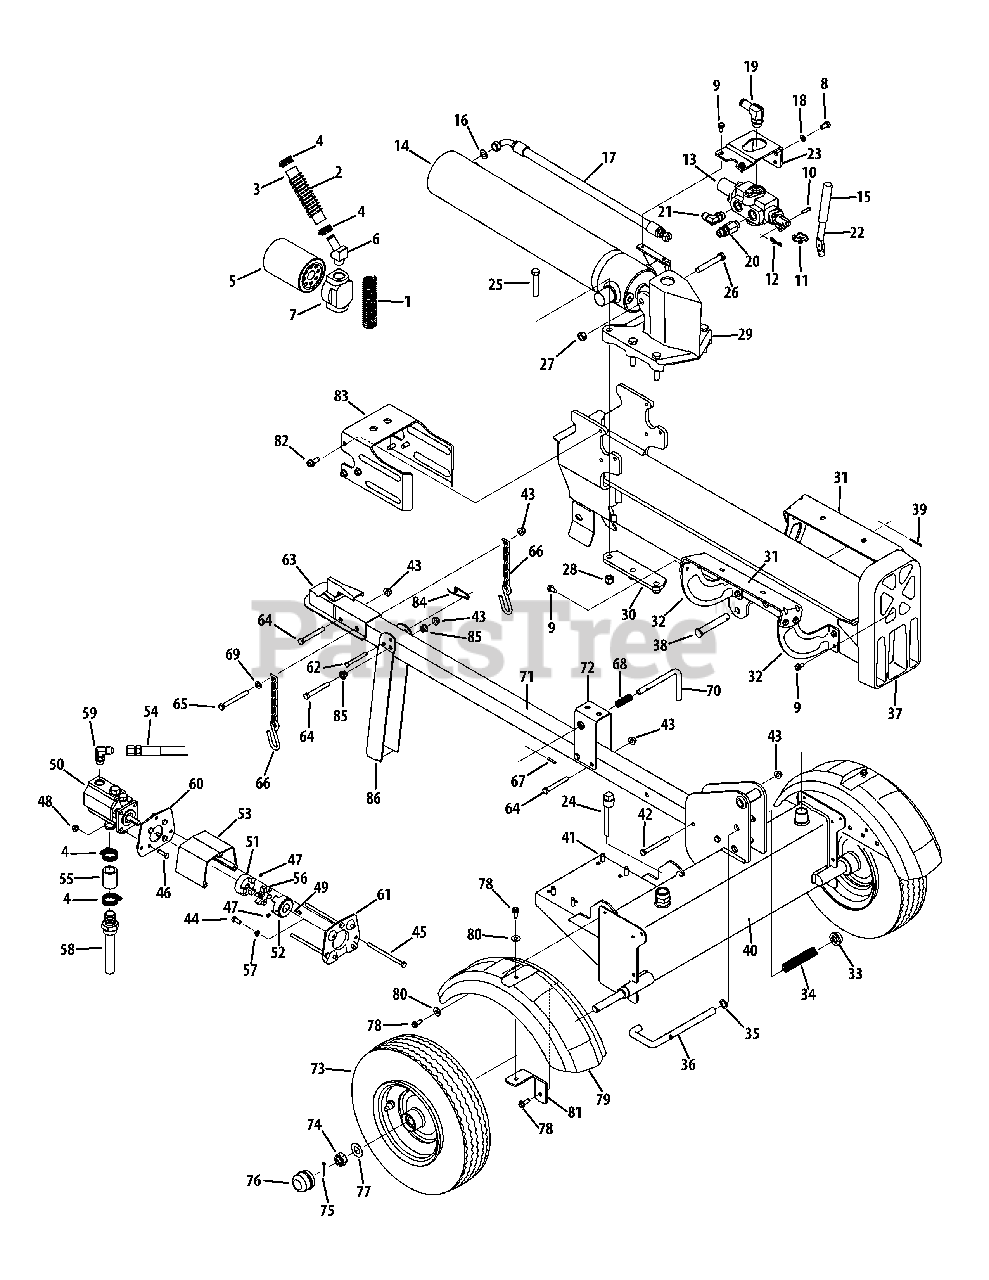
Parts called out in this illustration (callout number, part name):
1	Hose Guard
2	Hose Guard
3	Return Hose
4	Hose Clamp
5	Oil Filter
6	Hydraulic Fitting
7	Filter Housing
8	Hex Screw, 3/8-16 x .75
9	Hex Washer Screw, 5/16-18 x .750
10	Clevis Pin, .25 x 1.00
11	Valve Handle Link
12	Cotter Pin
13	Control Valve
14	Hydraulic Cylinder, 4.5 x 24
15	Grip, .625
16	Hydraulic O-Ring
17	Hydraulic Hose
18	Lock Washer, 3/8
19	Hydraulic Fitting, 7/8 x .75
20	Hydraulic Fitting, 3/4
21	Hydraulic Fitting, 3/4 x 13/16
22	Hydraulic Valve Control
23	Valve Bracket
24	Plug w/ Dipstick
25	Hex Screw, 1/2-20 x 2.75
26	Hex Screw, 1/2-13 x 3.25
27	Hex Lock Nut, 1/2-13
28	Hex Lock Nut, 1/2-20
29	Log Splitter Wedge
30	Log Splitter Wedge Plate
31	Log Tray Bracket
32	Log Splitter Tray Bracket
33	Push Cap, 5/8
34	Compression Spring, .625 x 4.0
35	Flat Washer, .635 x .930 x .060
36	Beam Lock Rod
38	Clevis Pin, .625 x 4.25
39	Cotter Pin, 1/8 x 1.25
40	Tank Assembly
41	Hex Washer Screw, 3/8-16 x 1.000
42	Hex Screw, 3/8-16 x 3.50
43	Flange Lock Nut, 3/8-16
44	Hex Screw, 5/16-24 x .75
45	Hex Screw, 5/16-18 x 4.00
46	Hex Screw, 5/16-18 x 1.00
47	Set Screw, 1/4-20 x .38
48	Flange Lock Nut, 5/16-18
49	Square Key, 3/16 x .75
51	Coupling, .500
52	Coupling, .750
53	Coupling Shield Spacer
54	Hydraulic Hose
55	Input Hose, 1.0
56	Spider Bushing
57	Lock Washer, 5/16
58	Inlet Filter
59	Hydraulic Fitting
60	Rear Coupling Support Bracket
61	Front Coupling Support Bracket
62	Clevis Pin
63	Hitch Coupling Assembly
64	Hex Screw, 3/8-16 x 3.00
65	Hex Screw, 3/8-16 x 3.50
67	Spirol Pin, 3/16 x 1.00
68	Compression Spring, .66 x 1.9
69	Flat Washer, .375 x .738 x .063
70	Latching Rod
71	Tongue Tube, 2.0 x 2.0
73	Complete Wheel Assembly
73	Dust Seal
73	Roller Bearing
74	Slotted Nut, 3/4-16
75	Cotter Pin, 5/32 x 1.25
77	Flat Washer, .760 x 1.50 x .030
78	Hex Washer Screw, 5/16-18 x 1.000
80	Thrust Washer, .343 x .880 x .062
81	Fender Mount Bracket
82	Hex Washer Screw, 3/8-16 x 1.000
83	Dislodger Bracket
84	Spring Pin
85	Plastic Bushing, .380 ID
